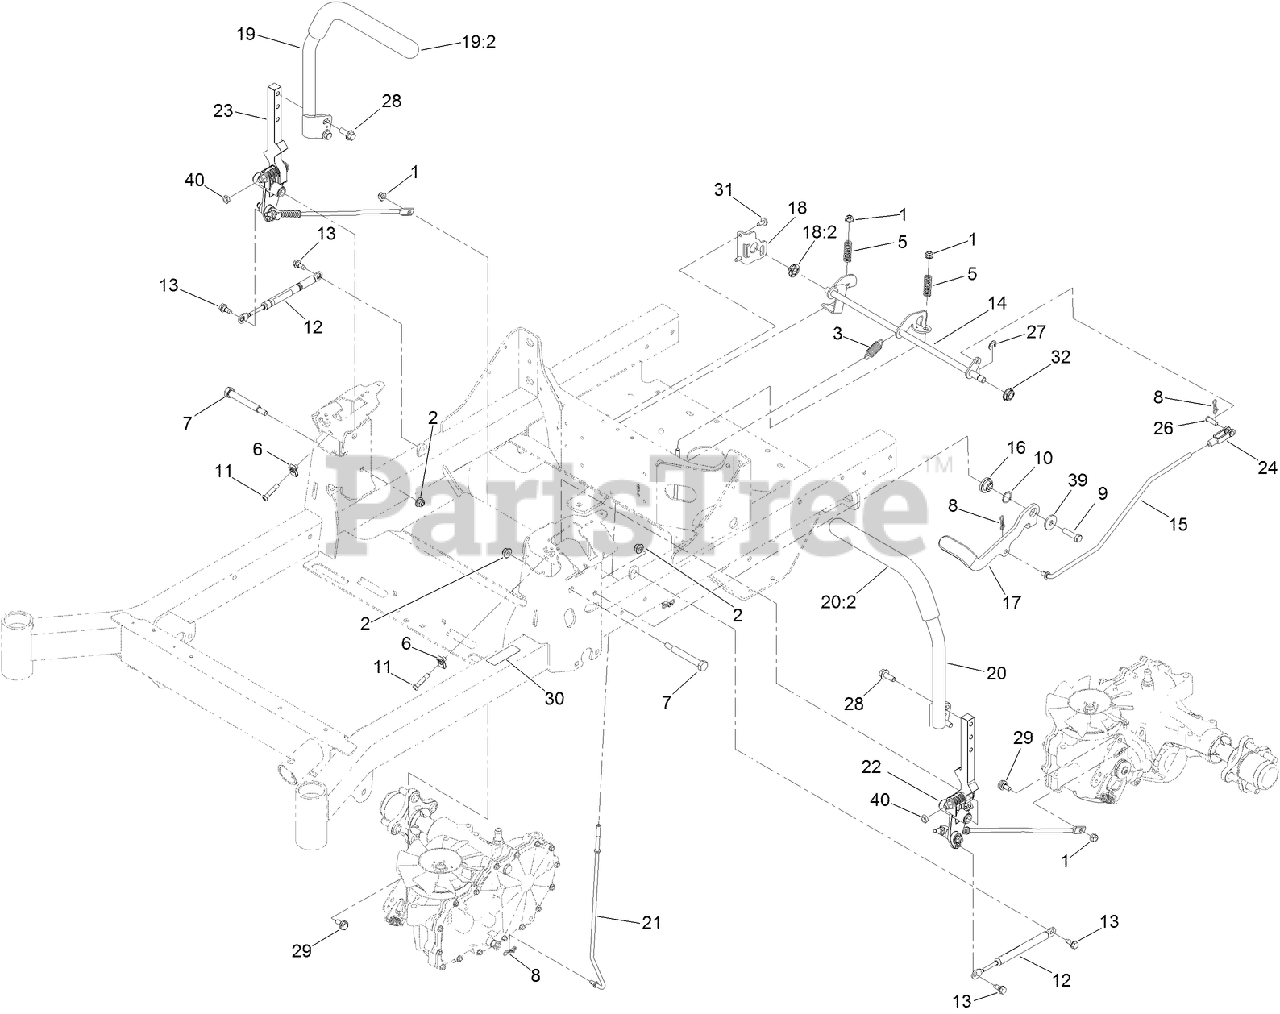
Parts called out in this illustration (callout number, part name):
1	NUT-HF, NI
2	NUT-HF, NI
3	SPRING-EXTENSION
5	SPRING-COMPRESSION
7	BOLT-PIVOT
8	PIN-COTTER, LOCKING
9	SCREW-HH
10	WASHER-WAVE
11	SCREW-HSBH
12	DAMPER
13	SCREW-SHOULDER
14	SHAFT-BRAKE
15	LINKAGE-BRAKE, UPPER
16	PIVOT-FLANGE
17	LEVER-BRAKE (WITH GRIP)
18	BRACKET-BRAKE
18:2	BEARING-SPHERICAL
19	RH CONTROL HANDLE ASM
20	LH CONTROL HANDLE ASM
21	LINKAGE-BRAKE, LOWER
22	Deck ASM
23	Deck ASM
24	YOKE-ADJUSTABLE
26	PIN-CLEVIS
27	RING-RETAINING, EXTERNAL
28	SCREW-HHF
29	BOLT-SHOULDER,HFH
30	DECAL-BRAKE, PARKING
31	SCREW-TORX
32	BEARING-SPHERICAL
39	WASHER
40	NUT-JAM
